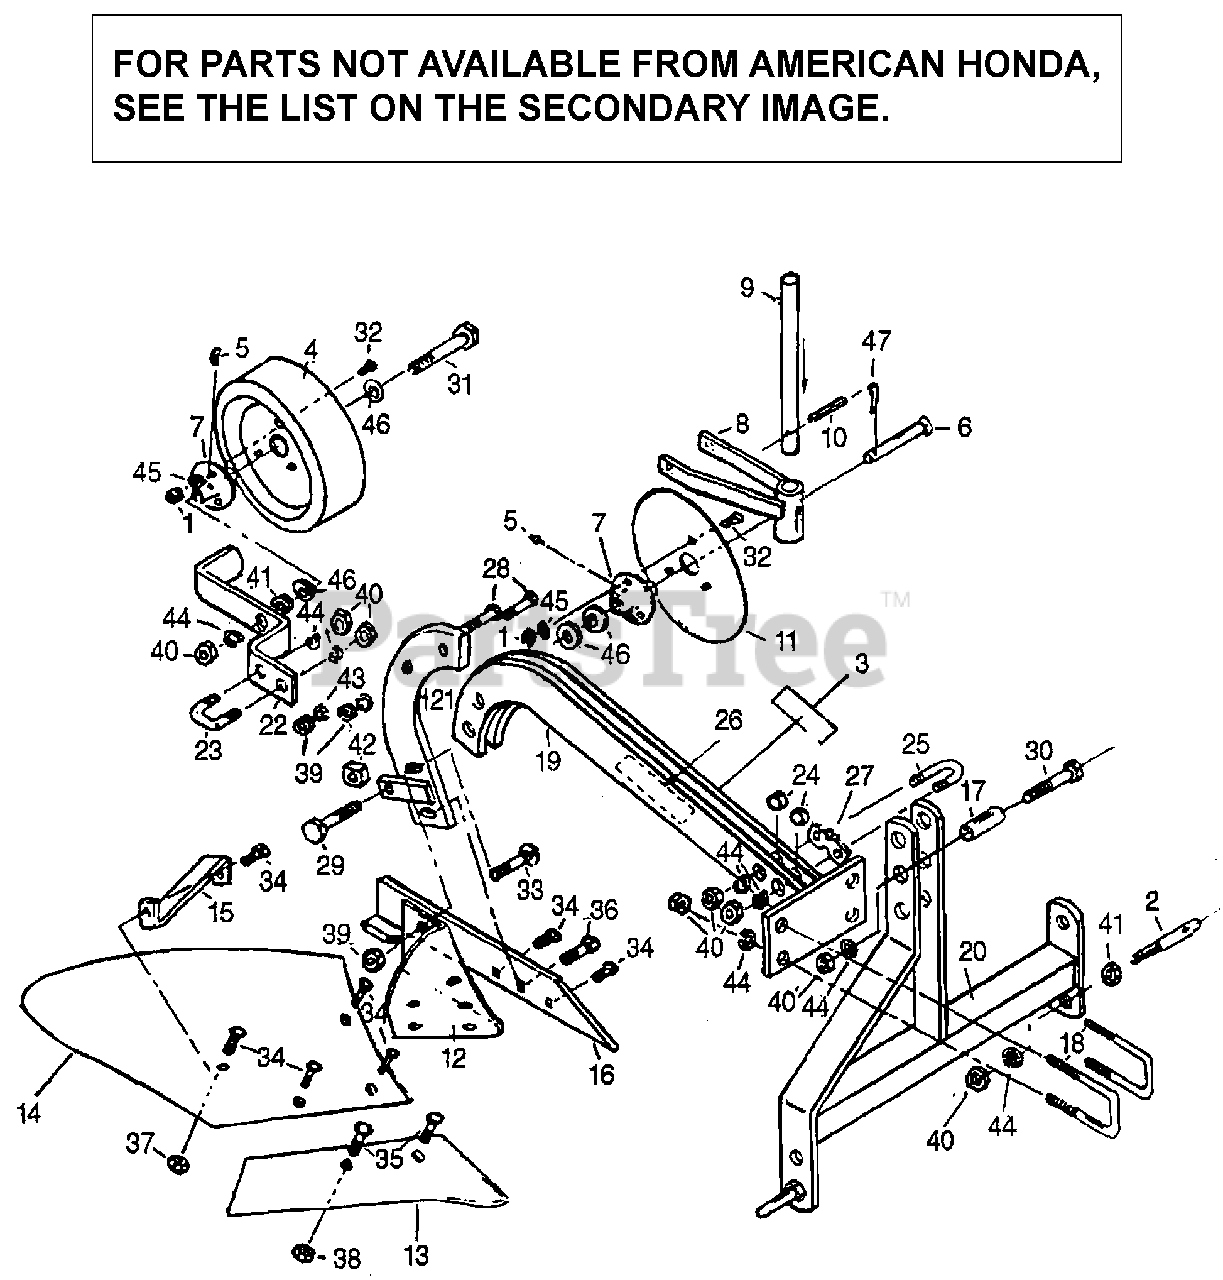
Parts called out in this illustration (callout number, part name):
2	LINK, PIVOT
4	GAUGE, WHEEL
5	FITTING, GREASE
6	BOLT, CARRIAGE BLANK
7	HUB (NOT AVAILABLE)
9	COULTER, STANDARD
11	BLADE, COULTER
13	PLOW SHARE (12") (NOT AVAILABLE)
14	MOLDBOARD
16	LANDSIDE ASSY.
18	U-BOLT (NOT AVAILABLE)
25	U-BOLT, COULTER (NOT AVAILABLE)
27	CLAMP, COULTER
34	BOLT, PLOW (3/8X1")
35	BOLT, PLOW (7/16X1")
36	BOLT, PLOW (1/2X2")
37	NUT, HEX. (3/8")
38	NUT, HEX. (7/16")
39	NUT, HEX. (1/2")
42	NUT, SQUARE (5/8")
